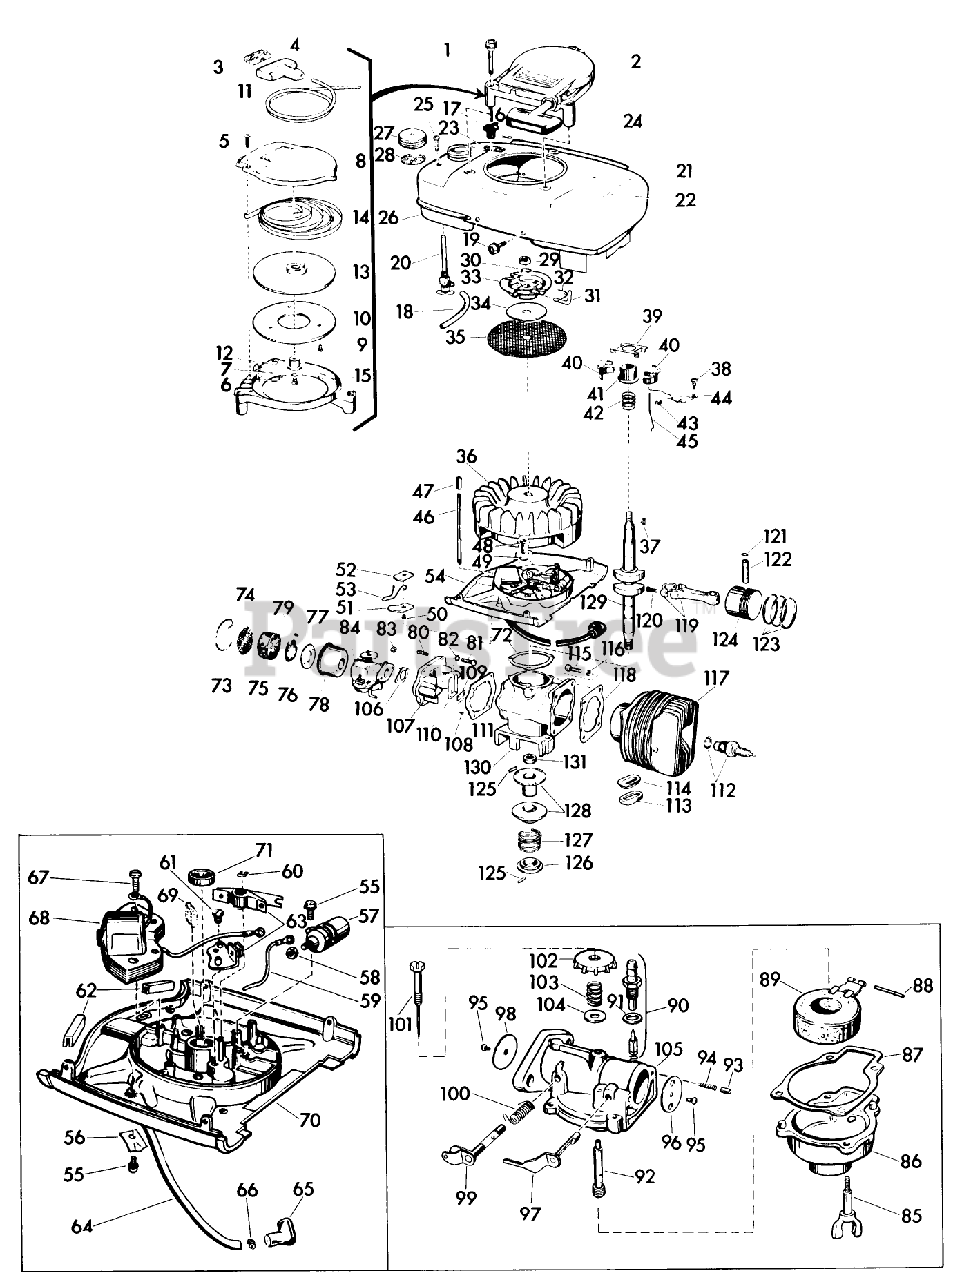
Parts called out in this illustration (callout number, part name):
6	Screw-Pulley to Cap
7	Washer-Lock, Pulley
14	RECOIL SPRING
15	Base-Starter
16	Cotter Pin-Choke Knob
17	KNOB, CHOKE BAR
19	SCREW S
20	VALVE&SCREEN SM
22	Decal-Instruction
23	Decal-Off-on
24	Decal-"Lawn-Boy"
27	Gas Cap
31	PIN - STARTER
41	COLLAR S
43	WEAR BLOCK S
44	GOVERNER LEVER AY
45	GOVERNOR ROD S
48	Screw-Pulley to Cap
49	Washer-Lock, Pulley
50	Screw Shut-off Switch
60	Spring Clip-Breaker Post
63	BREAKER AY. S
65	Cover-Rubber
69	Oiler Wick
72	GASKET S
75	ELEMENT
77	BACK-UP PLATE
80	SCREW S
83	STOP NUT
95	Screw-Choke Disc
97	CHOKE SHAFT&LVR AY
100	SPRING
101	NEEDLE AY. S
103	Spring-Ndl. Adj.
104	Washer-Needle Adjustment
106	GASKET S
109	PLATE-BACKUP, REED
112	Spark Plug
116	Washer-Lock, Cylinder to Crankcase
117	Cylinder and Sleeve Assembly
120	Screw-Connecting Rod
125	Pin-Pulley Drive
126	Retainer-Spring (Drive Pulley)
127	Spring-Comp. (Drive Pulley)
129	Crankshaft
